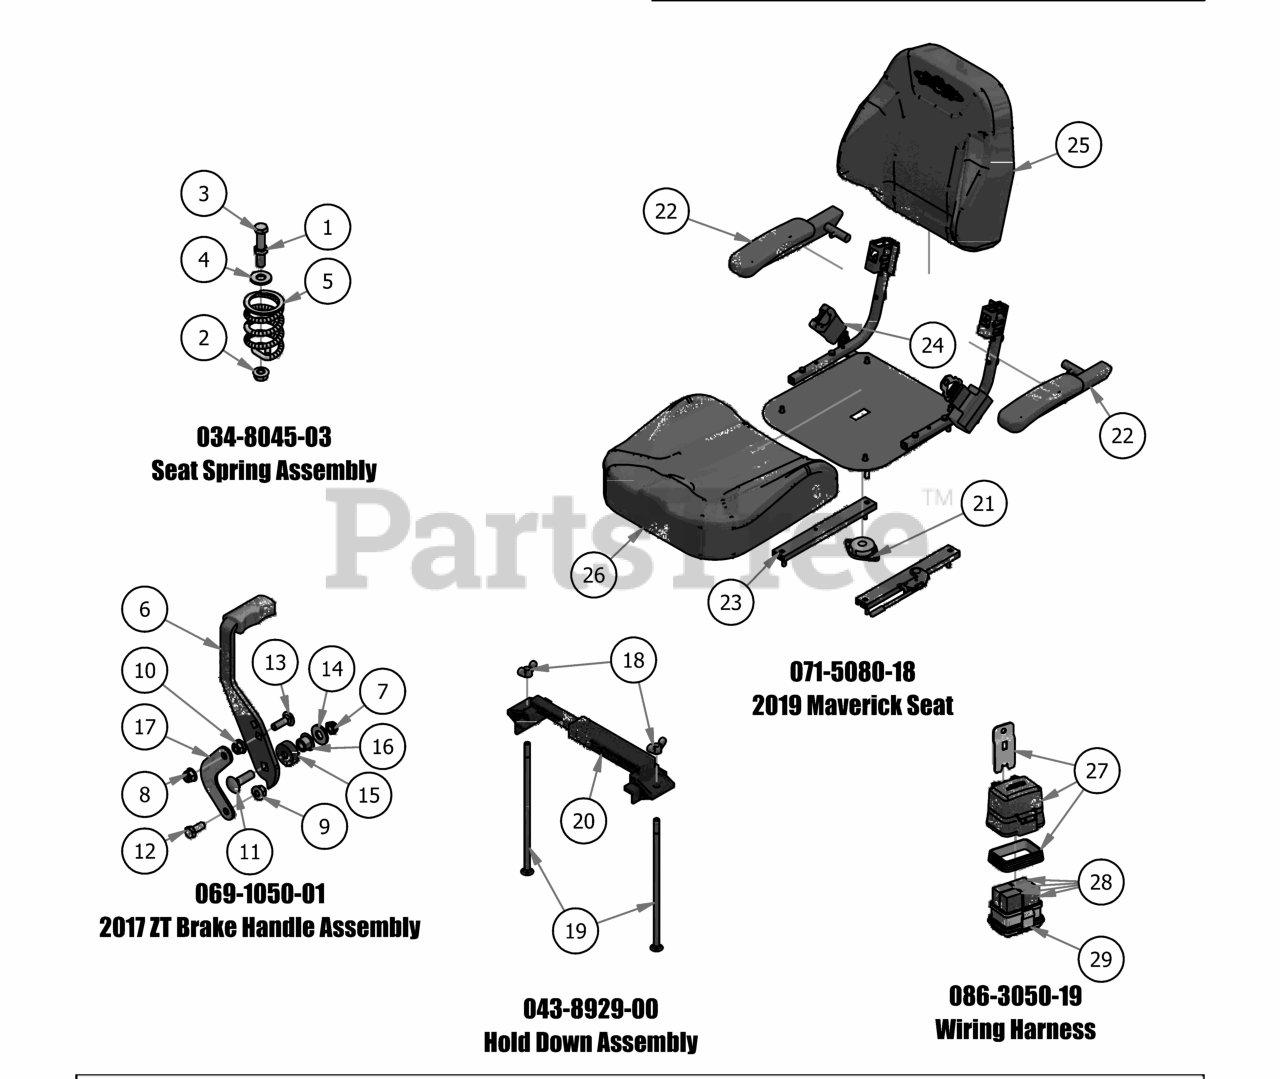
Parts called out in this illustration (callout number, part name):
1	3/8-16 Half Jam Nut
2	3/8" Flange Nut
3	3/8"-16 x 2" Gr 5 Hex Bolt
4	3/8" Flat Washer
5	Seat Spring
6	Brake Handle
7	3/8-16 Centerlock Half Nut
8	5/16-18 Nylon Insert Flange Nut (Black Cap)
9	5/16" Nylon Flange Nut
10	5/16" Flange Nut
11	3/8" x 1 1/4" Carriage Bolt
12	5/16" x 3/4" Hex Bolt
13	5/16" x 1" Carriage Bolt
14	3/8" Flat Washer
15	2015 Brake Lever Spacer
16	Bronze Bushing SF-1220-8
17	Brake Cable Adapter Bracket
18	1/4" Wing Nut
19	1/4-20 X 8 Carriage Bolt
20	Battery Hold Down
21	Seat Safety Switch
22	Seat Arm Pair
23	Seat Rails
25	Seat Back Cushion
26	Seat Cushion
27	Relay Block Cover Replacement Kit
29	Wiring Harness (Includes Cover Replacement Kit & Relays
